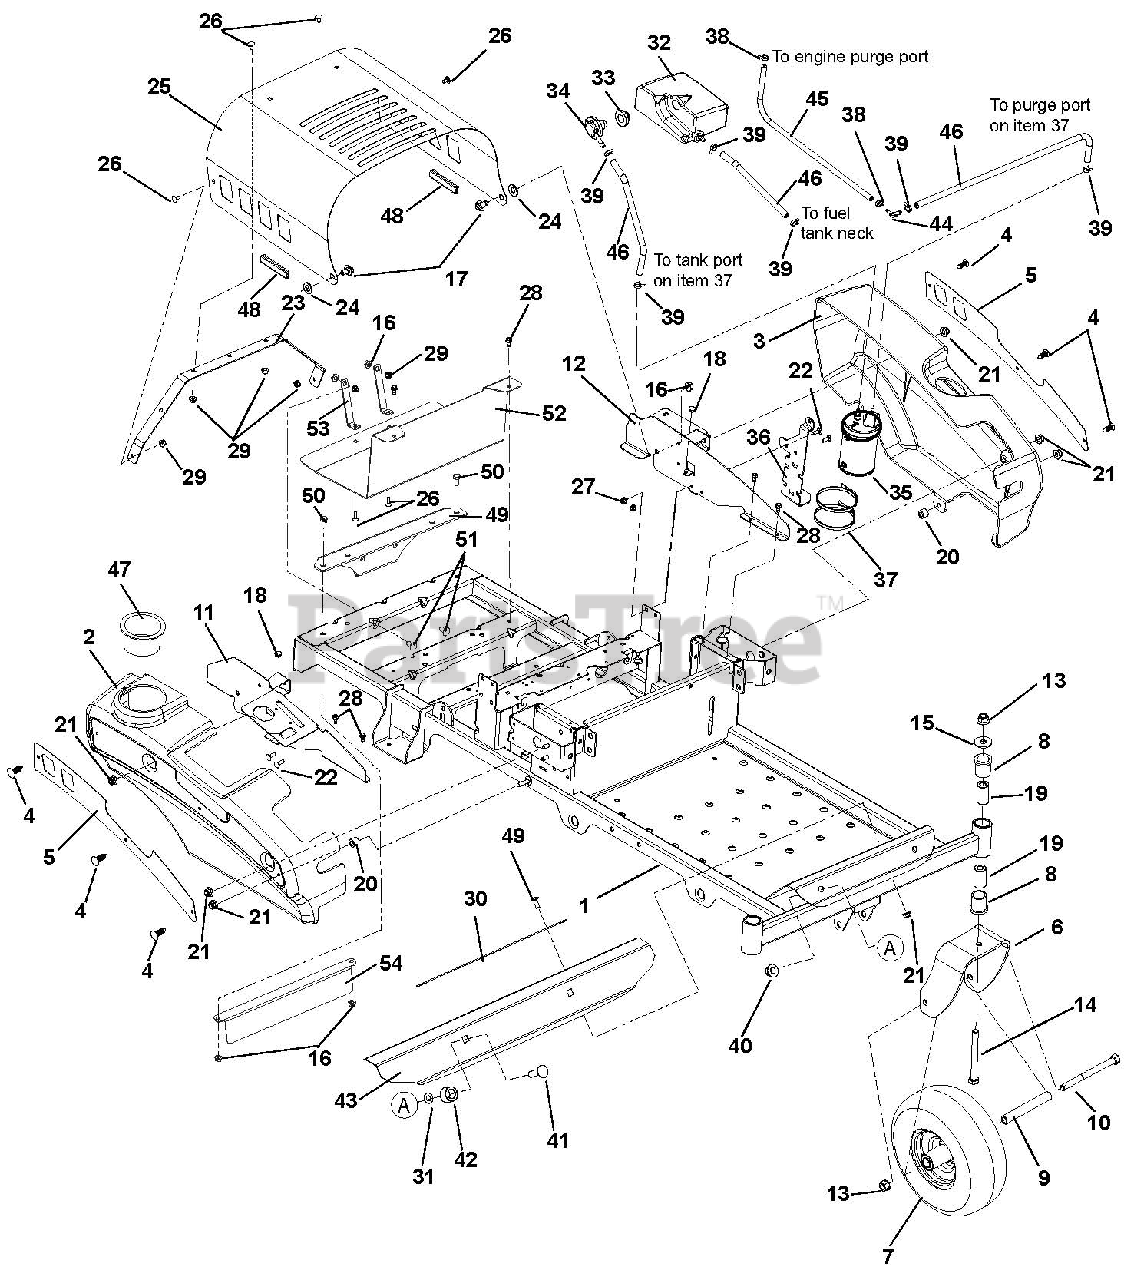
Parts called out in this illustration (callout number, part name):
1	KIT, ZOOM/ZT FRAME W/ DECALS
2	FENDER, RH
3	FENDER, LH
4	RIVET, .25 NYLON PANEL
5	PLATE, FENDER
6	WMT, CASTER FORK
7	TIRE/WHEEL ASSY, 11X4-5
7	TIRE, 11X4-5 TURF TREAD
7	TUBE 11 X4.0-5
8	BSHG-FLG 1.00X1.25X1.50X1.50
9	SPACER, ROLLED WHEEL
10	@BLT-HEX .50-13X6.50 GR5 YWZC
11	WLDMT, RH FENDER MOUNT
12	WLDMT, LH FENDER MOUNT
13	@NUT-LK-TOP-FLG .50-13 YWZC
14	@BLT-HEX .50-13X5.00 GR5 YWZC
15	WSHR-FL-STL.511X1.441X.125 YWZ
16	@NUT-LK-TOP-FLG .38-16 YWZC
17	BOLT-SHLDR .375-16X.150
18	BUMPER GROMMET
19	SPACER, CASTER .50X1.00X1.84
20	BSHG-SLV .391X.688X.52 PM
21	@NUT-LK-NYL-FLG .31-18 YWZC
22	@BLT-RDHDSQNK .25-20X.75 G5YZ
23	BRACE, HOOD
24	WSHR-FL-NYL .518X1.000X.080
25	HOOD, ZOOM
26	@BLT-RDHDSQNK .25-20X.50 G5YZ
27	@NUT-LK-NYL-FLG .25-20 YWZC
28	SCR-TAP .25-20X.50 HWH TR YWZ
29	@NUT-LK-TOP-FLG .25-20 YWZC
30	GRIP, ADHESIVE (1" X 16" BLK)
31	NUT-PUSH, .50
32	EXPANSION TANK SUB ASSY
33	GROMMET, REMOTE VENT NITRILE
34	VALVE, COMBINATION
35	CARBON CANISTER, 300CC
36	BRKT-MOUNT, CANISTER BBZ
37	P-PLASTIC TIE STRAP LARGE
38	CLAMP-HOSE, SPRING .188
39	CLAMP, FUEL LINE
40	@NUT-LK-NYL-FLG .50-13 YWZC
41	@BLT-RDHDSQNK .50-13X1.75 G5YZ
42	TUBE, UPPER CONTROL PIVOT
43	FOOTREST
44	FITTING-3/16X1/4 90DEGREE VAC
45	HOSE, .188 LOW-PERM BULK GAS
45	HOSE, .188 LOW PERM BULK
46	HOSE, .25 LOW-PERM BULK GAS
47	CUPHOLDER
48	EDGING, CLUTCH PADDLE - 2.00"
49	BLT-RDHDSQNK .50-13X7.00
50	@BLT-HEX .38-16X1.00 GR5 YWZC
51	@BLT-RDHDSQNK .38-16X1.00 G5YZ
52	GUARD, HEAT SHIELD (ZOOM/ZT)
53	STRAP, HEAT SHIELD (ZOOM/ZT)
54	GUARD, HOT SURFACE (ZOOM/ZT)
